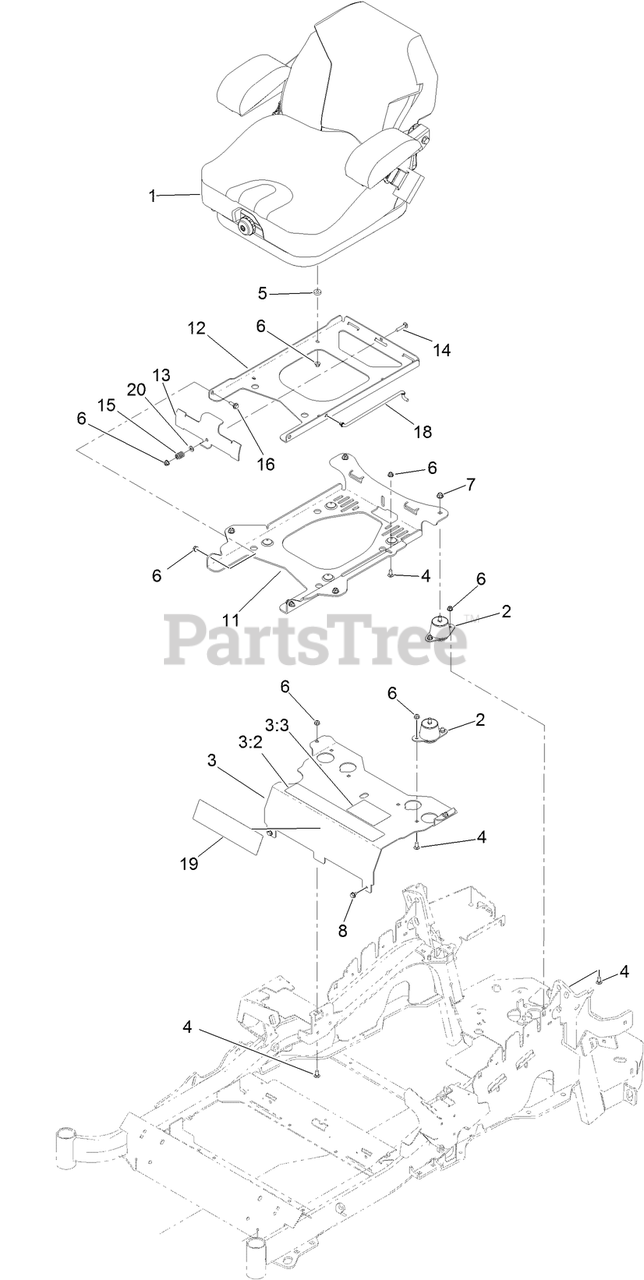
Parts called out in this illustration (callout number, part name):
1	SUSPENSION SEAT ASM
2	ISOLATOR-SEAT
3	SEAT MOUNT ASM
3:2	DECAL-CONSOLE
3:3	DECAL-SERVICE AID
4	SCREW-CARR
5	SPACER-PIN, MOUNTING
6	NUT-HF, NI
7	NUT-HF, NI
8	SCREW
11	PLATE-TILT, SEAT SUPPORT
12	PLATE-FRAME, SEAT
13	PLATE-LATCH, SEAT
14	BOLT-CARR
15	SPRING-COMPRESSION
16	SCREW-SHOULDER
18	ROD-PROP
20	WASHER-PLAIN
